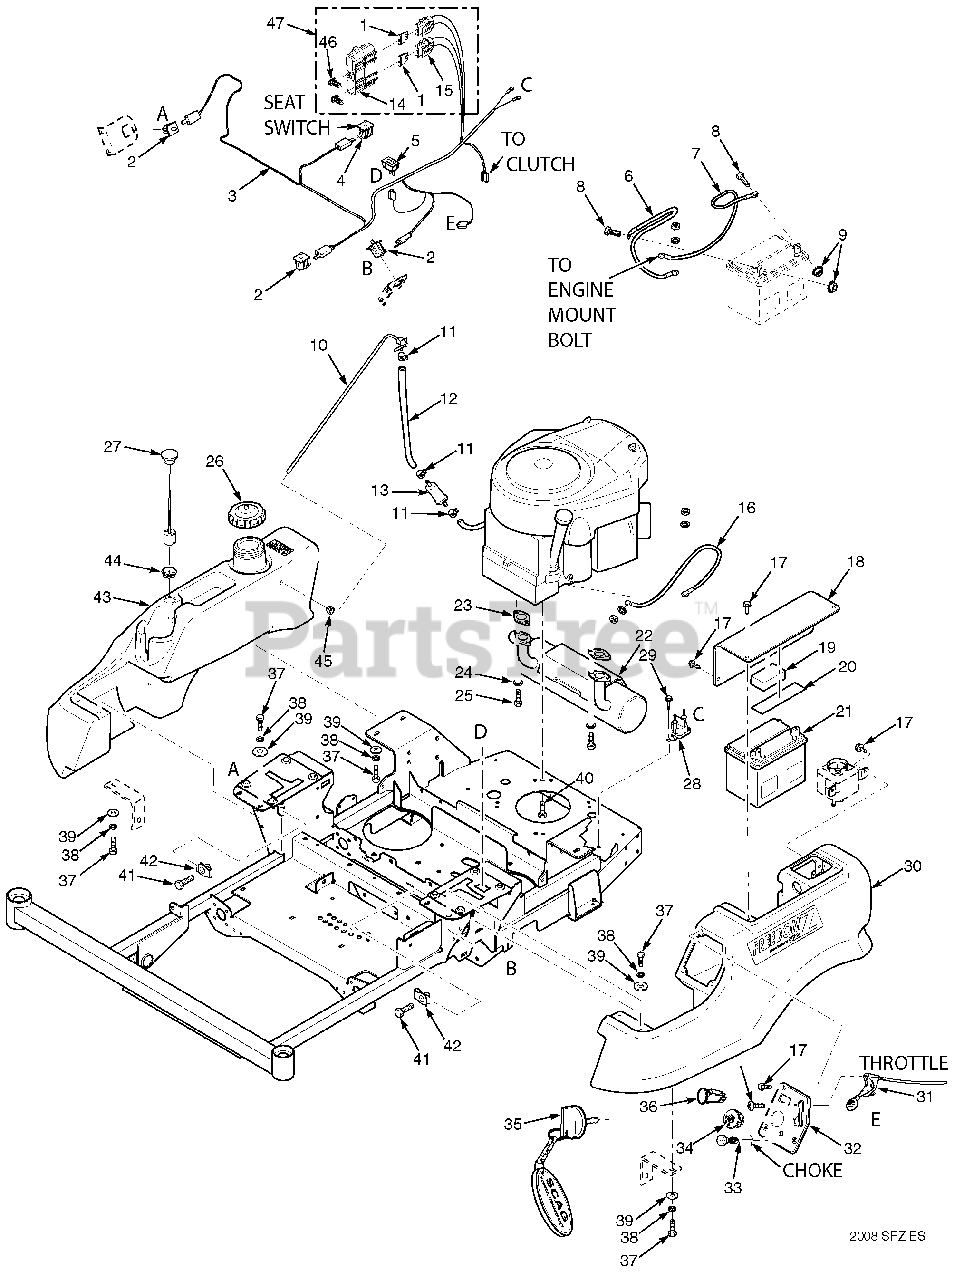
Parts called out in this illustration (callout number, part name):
1	Fuse, 20 amp
2	Switch
3	Wire Harness, Main
4	Switch, Seat
5	Hourmeter
6	Battery Cable, Red 25"
7	Battery Cable, Black 27"
8	Bolt, Hex Head 1/4-20 x 1/2"
9	Nut, 1/4-20
10	Fuel Tube Assembly
11	Clamp, Fuel Hose 1/4" ID
12	Fuel Hose, 1/4" ID Non-Perm
13	Fuel Filter
14	Cover, Sealed Double
15	Fuse Holder
16	Battery Cable, Red 9"
17	Bolt, Hex Head 1/4-20 x 1/2" Serr. Flange
18	Battery Cover
19	Pad, Battery Hold Down
20	Rubber Pad
21	Battery
22	Muffler, Briggs & Stratton
23	Exhaust Gasket
24	Lockwasher
25	Bolt
26	Cap, Fuel Tank
27	Fuel Gauge Assembly
28	Solenoid
29	Bolt, Self Tapping 1/2-20 x 3/4" Shakeproof
30	Tank, LH
31	Throttle Cable, Briggs & Stratton
32	Instrument Panel w/Decal
33	Choke Cable, Briggs & Stratton
34	Ignition Switch
35	Key, Ignition
36	PTO Switch
37	Bolt, Hex Head 5/16-18 x 3/4"
38	Lockwasher, 5/16" Spring
39	Flatwasher, 5/16-.375 x .875 x .083
40	Bolt, Hex Head 5/16-18 x 1-1/2"
41	Bolt, Hex Head 3/8-16 x 1-1/4" Special Lock
42	U-Nut, 3/8-16
43	Fuel Tank Assembly, RH
44	Grommet
45	Bushing, 0.56" Dia. Viton
46	Clip, Wire
47	Double Fuse Assy.
